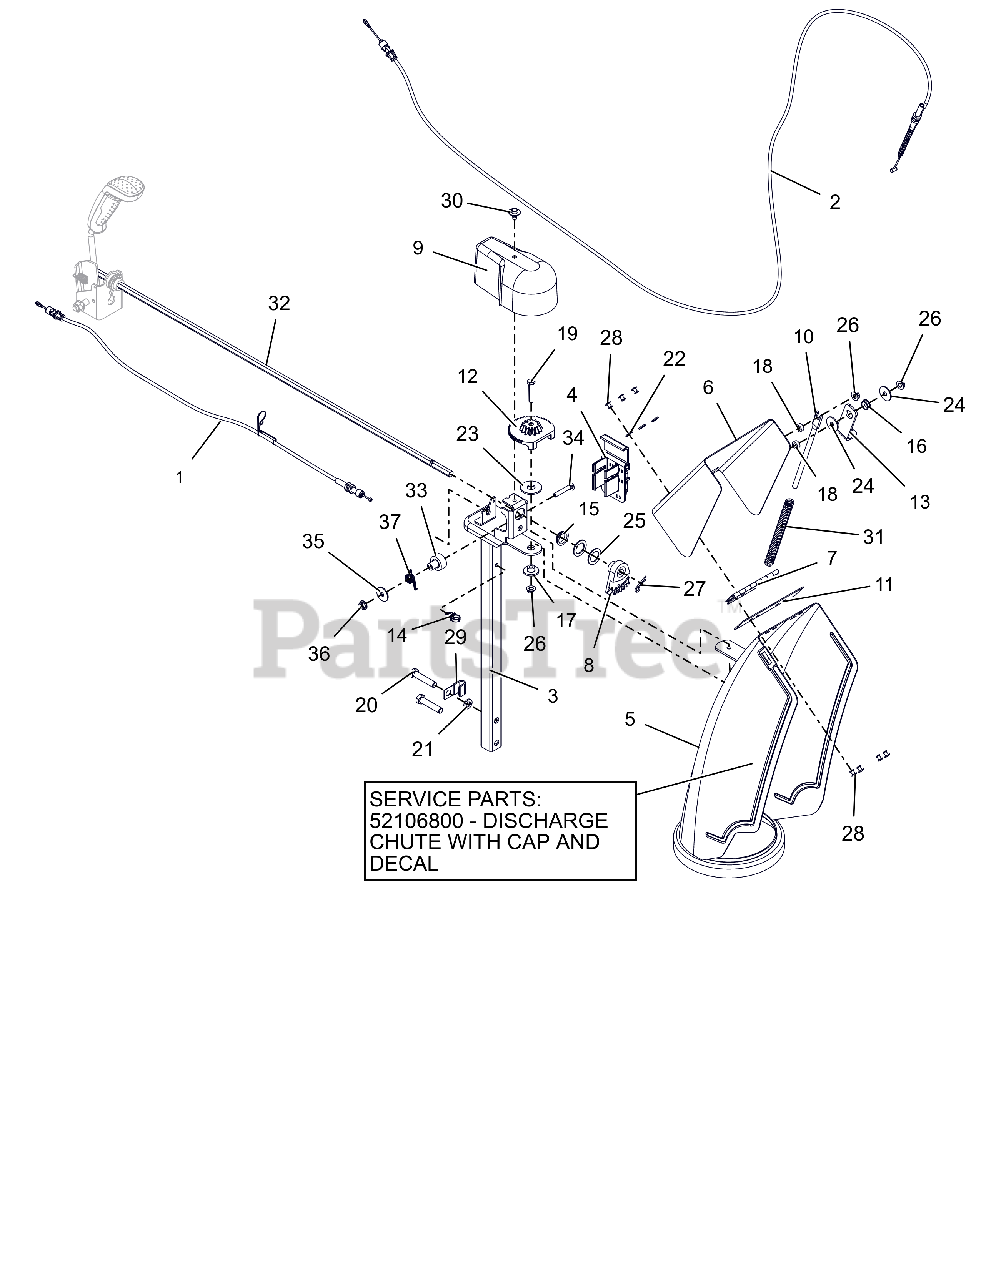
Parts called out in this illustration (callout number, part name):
1	CABLE, CHUTE LOCK, PRO
2	CABLE, DEFLECTOR - DELUXE
3	PEDESTAL, CHUTE - QUICK STICK
4	HOLDER W LARGE SHEAR BOLT /NUT
5	CHUTE,DISCHARGE,NOTCHED,QT
5	KIT, DISCHARGE CHUTE W/DEF QT2
6	CAP, LARGE REMOTE (W/DECAL)
8	GEAR, CHUTE-ACTUATION
9	COVER, CHUTE GEAR
10	ROD, DEFLECTOR CAP
11	CAP SEAL 5.50
12	GEAR, CHUTE
13	BRACKET, CABLE ANCHOR
14	CLIP, CABLE GUIDE
15	BUSHING, POLYLINER-.75 SNAPIN
16	BUSHING, POLYLINER-.50 SNAPIN
17	BSHG-FLG .265X.477X.375X1.00
18	BSHG-SLV .265X.500X.219
19	@BLT-HEX .25-20X1.50 GR5 YWZC
20	@BLT-HEX .38-16X1.75 GR5 YWZC
21	@WSHR-LK .38X.094 REG YWZC
22	WSHR-FL-STL .196X.500X.06 YZ
23	WSHR-FLT-NYL .515X1.375X.093
24	WSHR-FL-STL .281X1.000X.063
25	WSHR-FL-STL.754X1.125X.062YWZC
26	@NUT-LK-CTR-FLG .25-20 YWZC
27	PIN-HAIR INT .08X.18X1.18 YWZC
28	RVT-POP .187 YZ
29	J-CLAMP
30	SCR-TAP .25-20X.50 LGHWH TR YZ
31	SG-COMP .08X.40X6.50 14#/IN
32	ROD, HEX - CHUTE ROTATION
33	BUSHING, LOCK ARM
34	@BLT-RDHDSQNK .25-20X1.50 G5YZ
35	WSHR-FL-STL .281X1.000X.063
36	@NUT-LK-CTR-FLG .25-20 YWZC
37	SG-TORS
